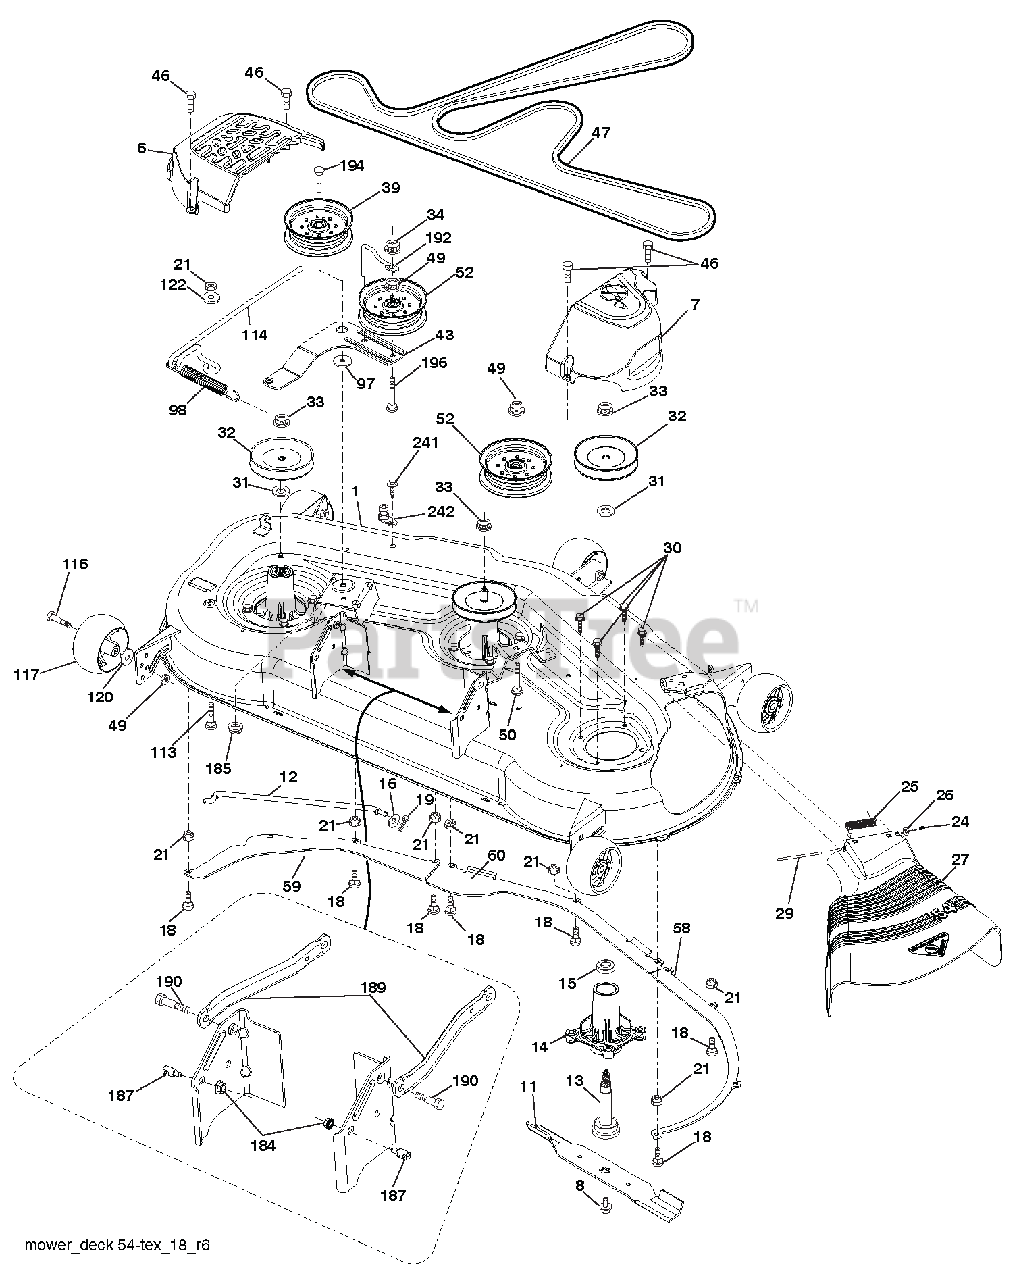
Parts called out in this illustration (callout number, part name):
1	DECK WELDMENT MOWER
6	COVER.MANDREL.LH.54"2006
7	COVER.MANDREL.RH.54"2006
8	BOLT/WASHER ASM.7/16-20.UNF
11	BLADE.BAGGING.54"
12	ROD ANTI-SWAY
13	SHAFT ASM.MANDREL.48/54"SVC
14	HOUSING.MANDREL.4PT.SERVICE
15	BEARING.BALL.MANDREL
16	Washer 13/32 x 13/16 x 12 Ga.
18	BOLT.RDHD.SQNK.5/16-18 X 5/8
19	PIN.COTTER.5/16.BOW TIE LOCK
21	Nut, Hex, Crownlock 5/16-18
24	CAP.SLEEVE..80X.112.BLK.MOWER
25	SPRING.TORSION.48"
26	NUT.PUSH.PHOS.& OIL
27	DEFLECTOR SHIELD
29	ROD.HINGE.42/46"
30	SCREW.THD ROLL.DOD PT.HEX
31	WASHER.SPACER.MANDREL
32	MANDREL.PULLEYS.42,44,50
33	NUT.FLANGE.LOCK.TOP
34	Nut, Hex, Crownlock 3/8-16
39	PULLEY.IDLER.4.50.HUB.SPECIAL
43	ARM.ILDER
46	SCREW.THD.ROLL.1/4-20 X 5/8
47	BELT.DRIVE.54"2006
49	Nut, Hex, Flangelock 3/8-16
50	BOLT.RD.HD.SQ.NK.3/8-16UNC X 2
52	PULLEY.IDLER.4.50.RAW
58	BAFFLE.RIGHT.54"
59	BAFFLE.LEFT.54"
60	BAFFLE.CENTER.54"MOWER
97	WASHER.FLAT.HARDENED
98	SPRING.DRIVE.DECK.2006
113	BOLT.CARR.5/16-18UNC X 1
114	ROD.TENSION.RELIEF
116	BOLT.SHOULDER.3/8-16X3-5/8.GR5
117	WHEEL.GAUGE.RALLY.
120	WASHER.13/32 X 1-1/4 X 12 GA.
122	BUSHING.RELIEF.TENSION
184	Nut, Lock Hex Flange 5/16-18 u
185	NUT.LOCK.FLANGE.7/16-14.GR5
187	STUD.FASTNER.W/'D'ANTI-ROTATIO
189	ARM.SUSPENSION.MOWER.REAR
190	BOLT.SHOULDER
192	KEEPER.BELT.IDLER.54"TL
194	BOLT CARR SQNK 3/8-16 X 2-1/4
196	BOLT.RDHD.SQNK.3/8-16X2-1/2.G5
242	PORT WASHOUT
